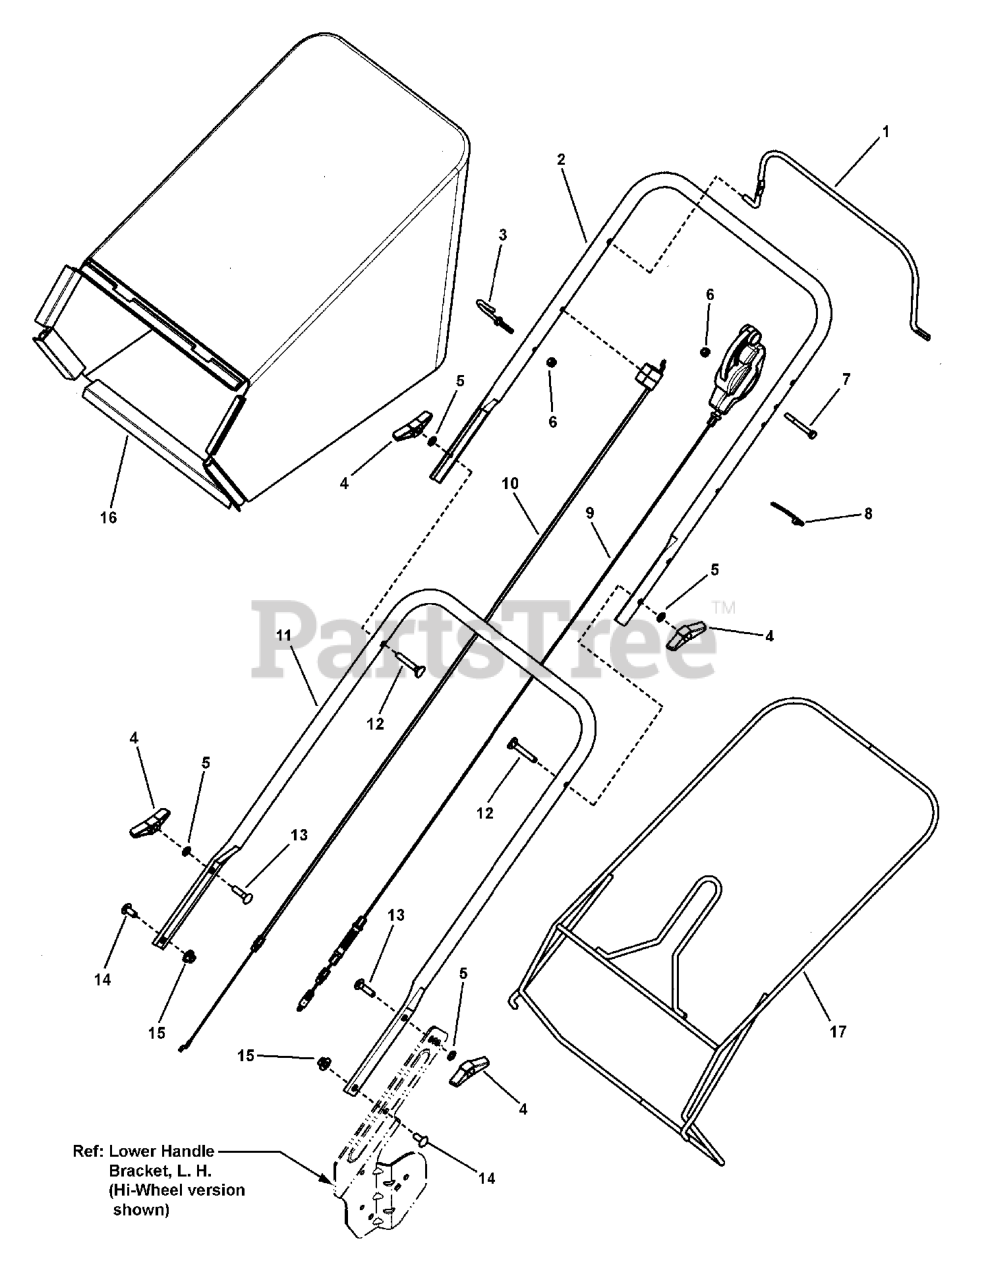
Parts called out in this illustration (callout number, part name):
1	BAIL, OPC Propelled
2	UPPER HANDLE, Propelled
3	GUIDE, Rope (1/4-20 thread)
4	KNOB, 5/16-18 Wing (Black)
5	WASHER, 5/16" Internal Tooth Lock
6	NUT, 1/4-20 Nyloc
7	SCREW, 1/4-20 x 2-1/4 Hex Head Cap, GR 5
8	WIRE TIE, 11 Inch Std Black Nylon
9	CONTROL, Drive, Single Speed Std Wheel
9	CONTROL, Drive, Single Speed Hi-Wheel
10	CABLE, Bail, Std Propelled (53.50" overall length)
10	CABLE, Bail, Hi-Wheel Propelled (58.00" overall length)
11	HANDLE, Lower
12	BOLT, 5/16-18 x 2" Curved Head Square Neck GR 2
13	BOLT, 5/16-18 x 1" Square Neck Carriage
14	BOLT 5/16-18 x 3/4" Round Head Short Square Neck
15	NUT, 5/16-18 Large Flange Center Lock
16	GRASS BAG, 22" Rear Discharge
17	WELDMENT, Frame, Grass Bag, 22" Walk-Behind
